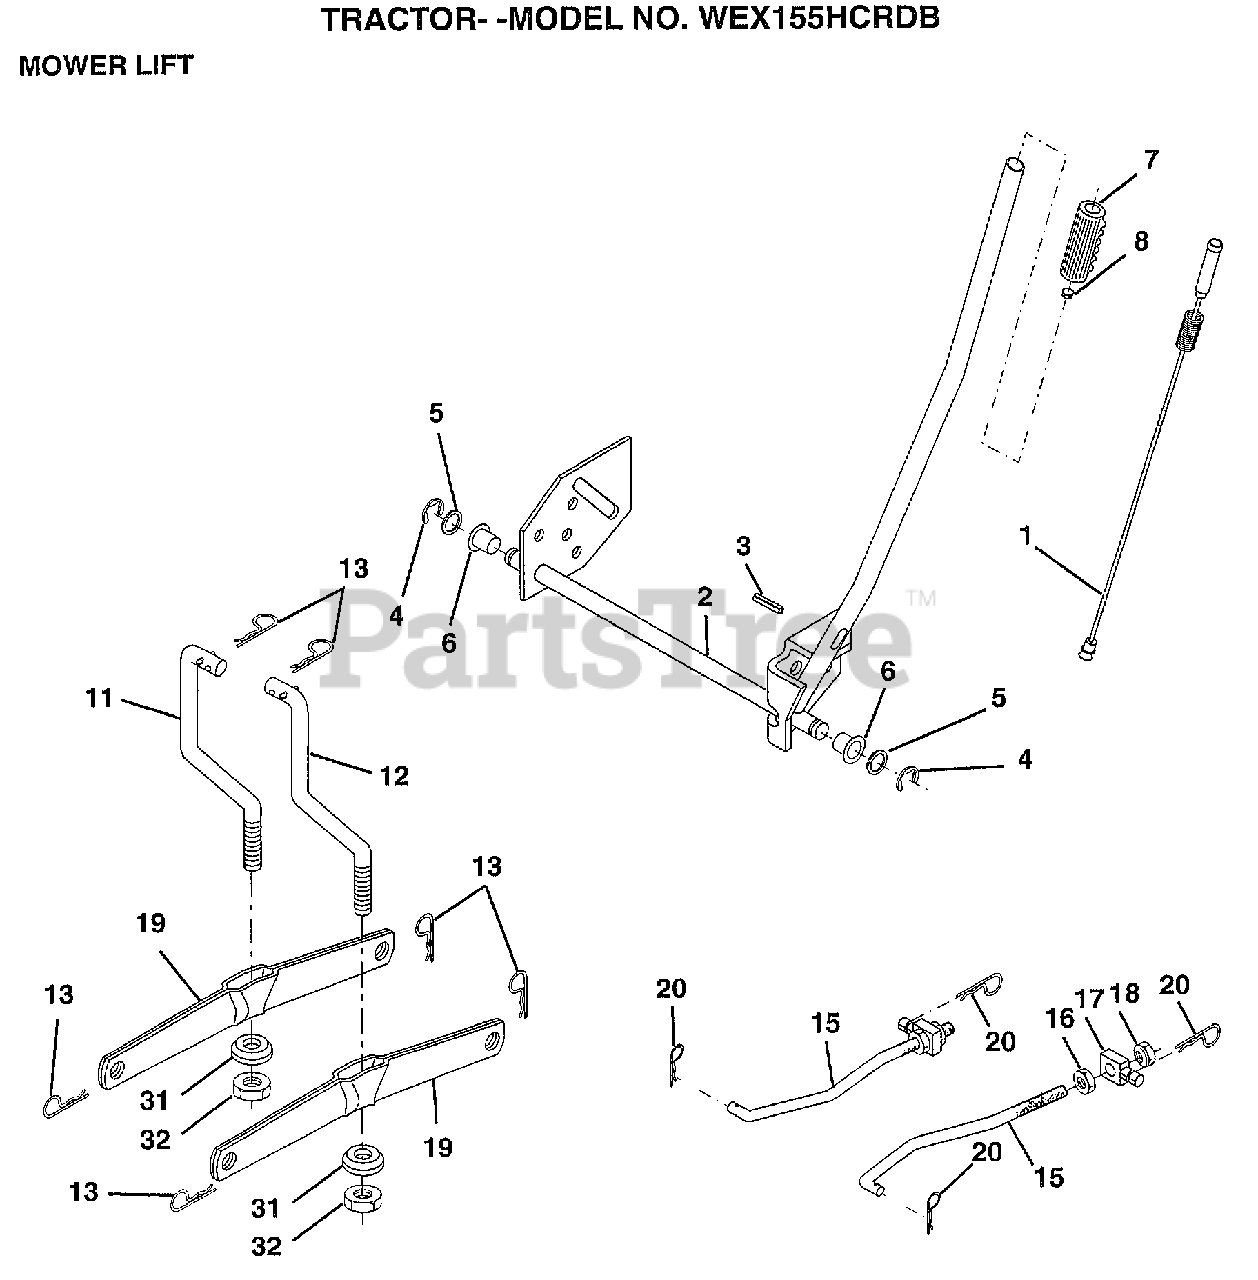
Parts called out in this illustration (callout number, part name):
1	WIRE ASM W.SPRING
2	"SHAFT ASM LIFT,RH"
3	PIN-GROOVE LT
5	WASHER
6	NYLON BEARING
7	GRIP
11	LINK.LIFT.LH.CRD
12	LINK.LIFT.RH.CRD
15	LINK.FRONT
16	NUT
17	TRUNION
18	NUT LTV
19	ARM SUSP REAR
20	RETAINER SPRING
31	BEARING PVT LH
32	NUT.CROWNLOCK.3/8
